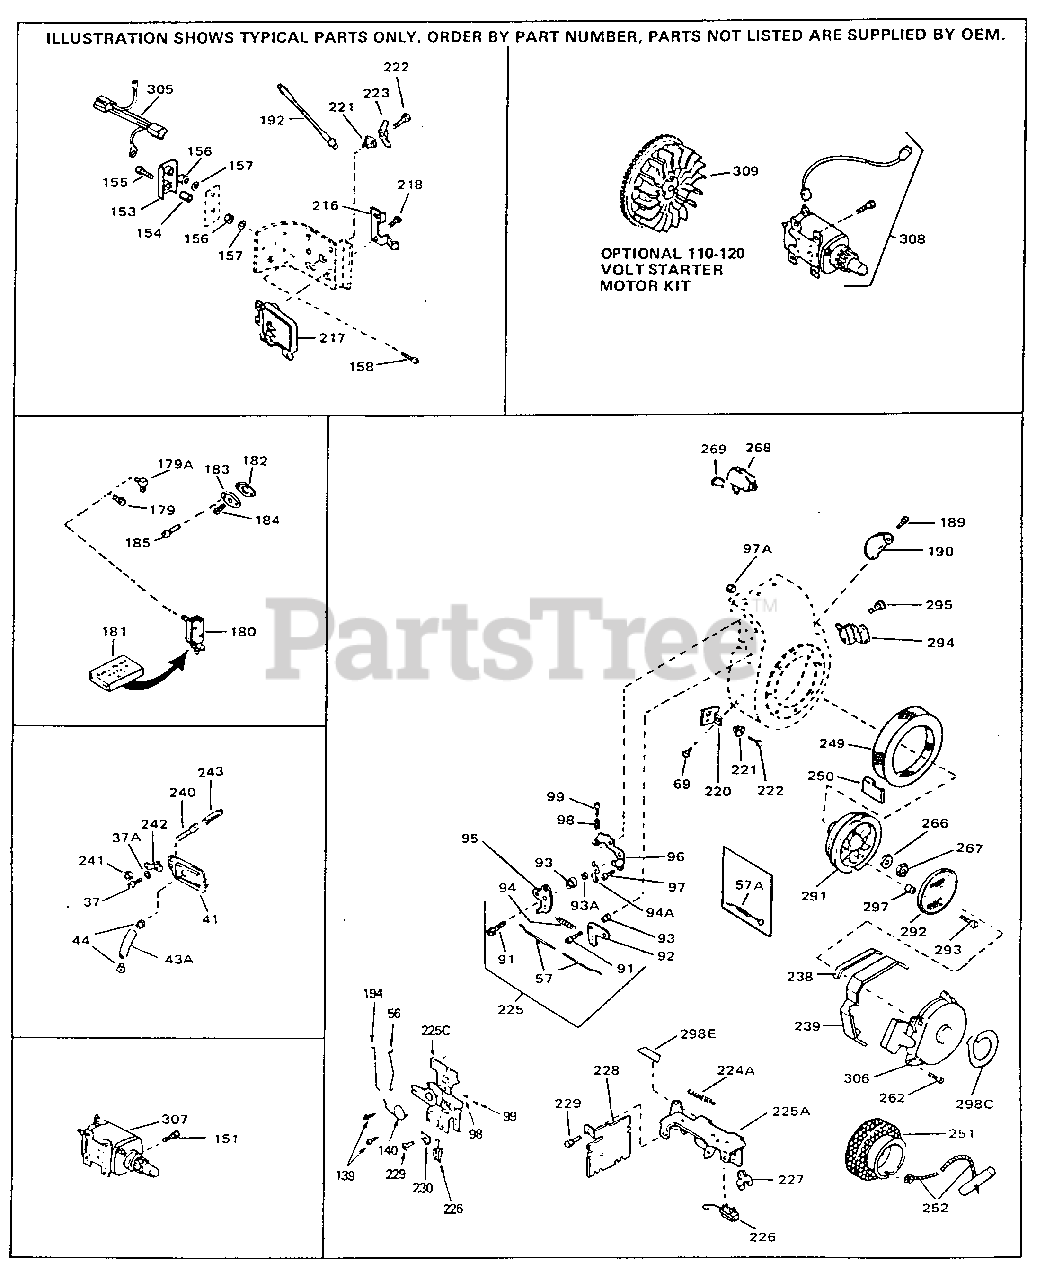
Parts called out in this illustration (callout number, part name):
37	Screw, 10-24 x 1/2" (Use as required)
37	Screw, 10-24 x 5/8" (Use as required)
41	Valve Cover
44	Grommet, Breather tube
56	Link, Throttle
69	Screw, T-40, 5/16-24 x 21/32"
98	Compression Spring (Used with 29500 s crew)(Use as required)
98	Compression Spring (Used with 650549 screw) (Use as required)
98	Compression Spring (Used with 650688 screw) (Use as required)
99	Screw, 10-32 x 1 (Use as required)
99	Screw, 8-32 x 3/4" (Use as required)
99	Screw, 5-40 x 7/16" (Use as required)
121E	Muffler (Incl. 124, 124A & 124B) (Thi s spark arrester mufflercan be used o n any model)
182	Gasket, Fuel pump cover Use as requir ed
183	Cover, Fuel pump pad Use as required
184	Plug, Pipe 1/8-27 (Use as required)
185	Screw, T-30, 1/4-20 x 1/2"
225	Control Bracket (Incl. 91 thru 97) As req.
226	Terminal Assy.
227	Terminal (Use as required)
229	Screw, 10-32 x 3/8"
230	Conduit Clip
262	Screw, 1/4-28 x 7/16"
266	Washer, Belleville
267	Nut, Hex
305	Harness Assy., Adapter Use as requir ed
306	Rewind Starter Refer to Division 5, S ection C, page 25 for breakdown
308	Starter Motor Kit (110-120 Volt) NOTE : This 110-120 volt starter motor ki t may have been added to this engine. This can be added only if cylinder has drilled and tapped starter mounti ng bosses and a ring gear flywheel ha s been added (see #309).
309	Flywheel Ring gear flywheel requiredo n engines using 110-120 volt starter motor kits listed above.
